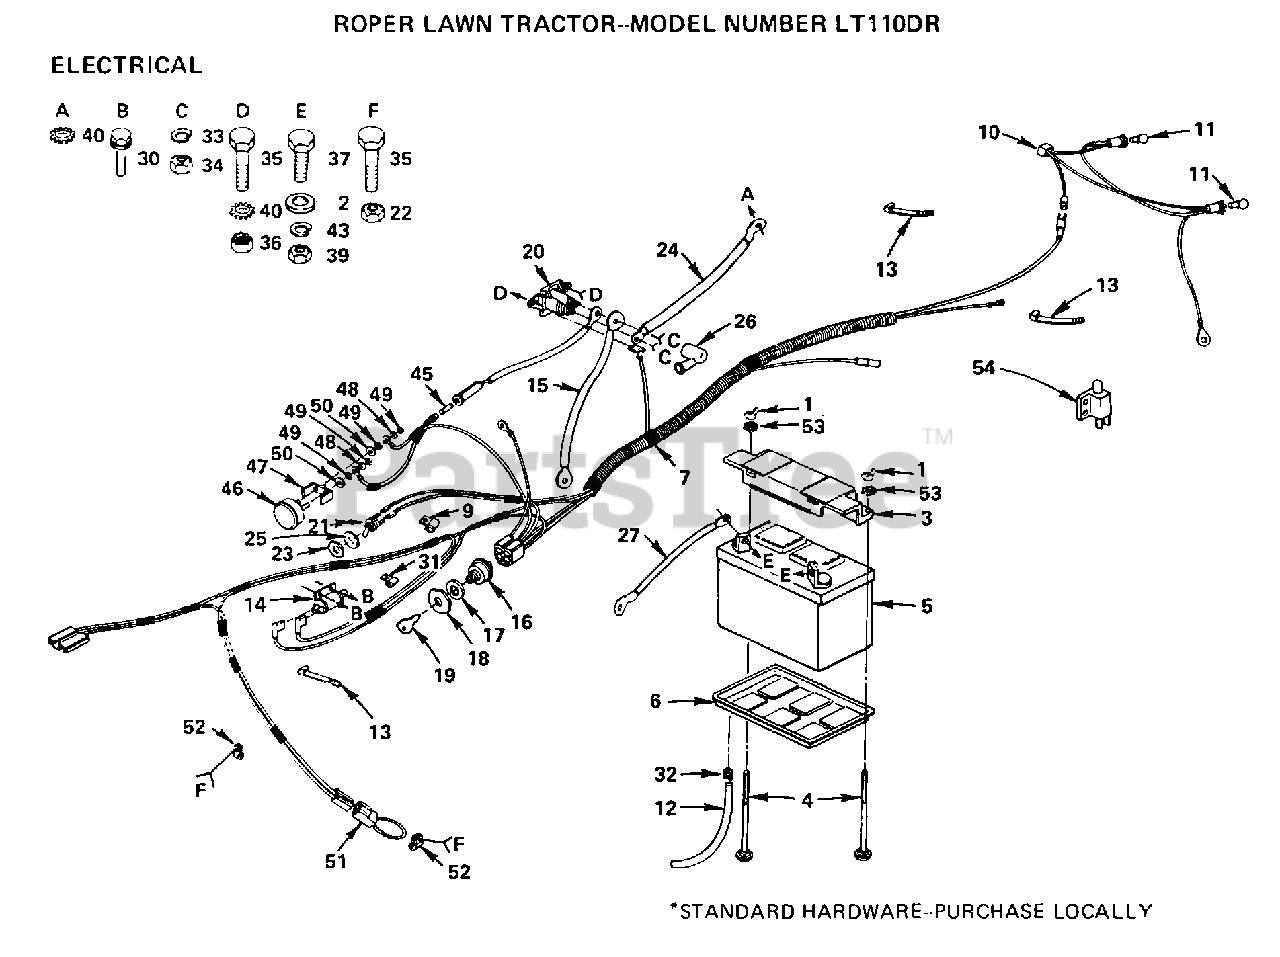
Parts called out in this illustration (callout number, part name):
2	WASHER
4	BOLT
6	"TRAY, BATTERY LT"
7	HARNESS, IGNITION
10	HARNESS T
13	WIRE TIE
15	"CABLE T, BATTERY"
17	LOCKWASHER
18	CONDUIT NUT L
21	LIGHT SWITCH T
27	CABLE ASSY LT
31	CLIP T
34	NUT
35	BOLT
36	NUT
37	BOLT LT
43	LOCKWASHER
45	FUSE-30 AMP
46	AMMETER T
52	CLIPT
53	LOCKWASHER GT
54	SWITCH-INTER. GT
